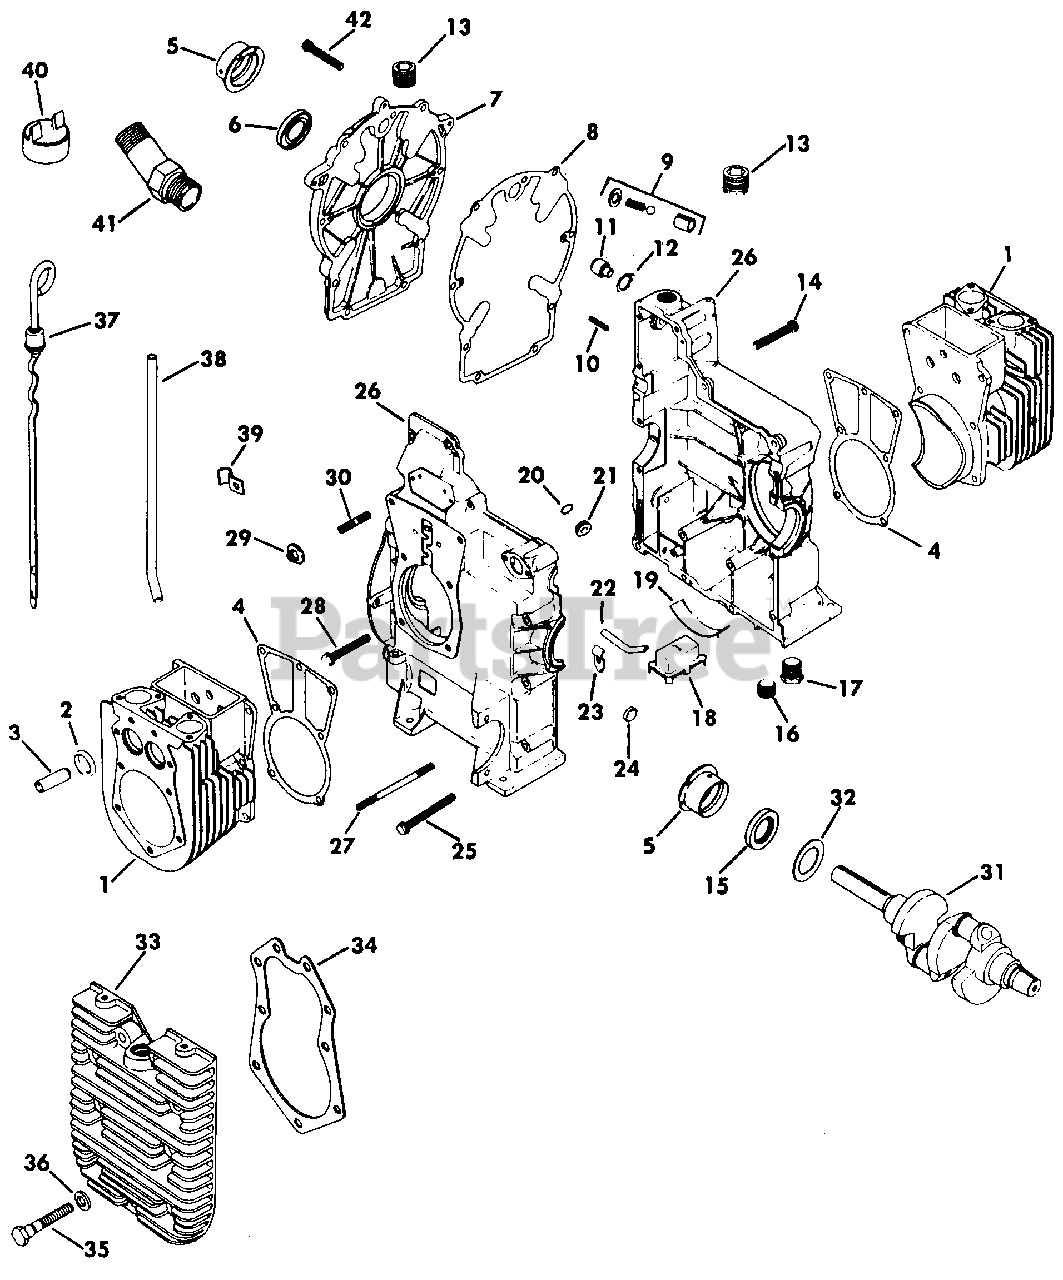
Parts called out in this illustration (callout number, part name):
1	Cylinder Assy, Barrel
2	Insert, Valve Seat
3	Guide, Valve
4	Gasket, Cylinder
5	Bearing, Sleeve
5	Bearing, Sleeve, .010 U/S
5	Bearing, Sleeve, .020 U/S
6	Seal, Rear Oil
7	Kit, Closure Plate
8	Gasket, Closure Plate
9	Kit, Oil Relief
10	Pin, 1/8 X 1-1/4 Pln Slt Spr
11	Shaft, Governor
12	Ring, Retaining
13	Plug, 1/16-27 C-Z Sq Skt Auto Drain
14	Screw, 5/16-18 X 2 Washer Hd
15	Seal, Front Oil
16	Plug, 3/8-27 Pln Hex Skt Auto Pipe
17	Plug, 3/8-18 Pln H/Hd Filler & Drain, Bottom Drain
18	Housing, Oil Pick-Up
19	Clip, Spring
20	O-Ring, 9/16 X 11/16 Class 3
21	Plug, 3/4 OD
22	Tube, Oil Pick-Up
23	Clamp, Oil Pick-Up Tube
24	Plug, 5/16 Cup
25	Screw, 5/16-18 X 3-1/2 Washer Head
26	Crankcase - Not Serviced Separately
27	Stud, 5/16-18 X 4-1/8
28	Screw, 3/8-16 X 3-5/8
29	Nut, 3/8-16
30	Stud, 3/8-16 X 1-15/16
32	Washer, Thrust, .123 OR
32	Washer, Thrust, .132 OR
32	Washer, Thrust, .141
33	Head, Cylinder
34	Gasket, Cylinder Head
35	Screw, Cylinder Head
36	Washer, Cylinder Head
37	Dipstick, Oil Level
38	Tube, Oil Level
40	Cap, Oil Filler
41	Tube, Oil Filler
42	Screw, 5/16-18 X 1 Washer Head
